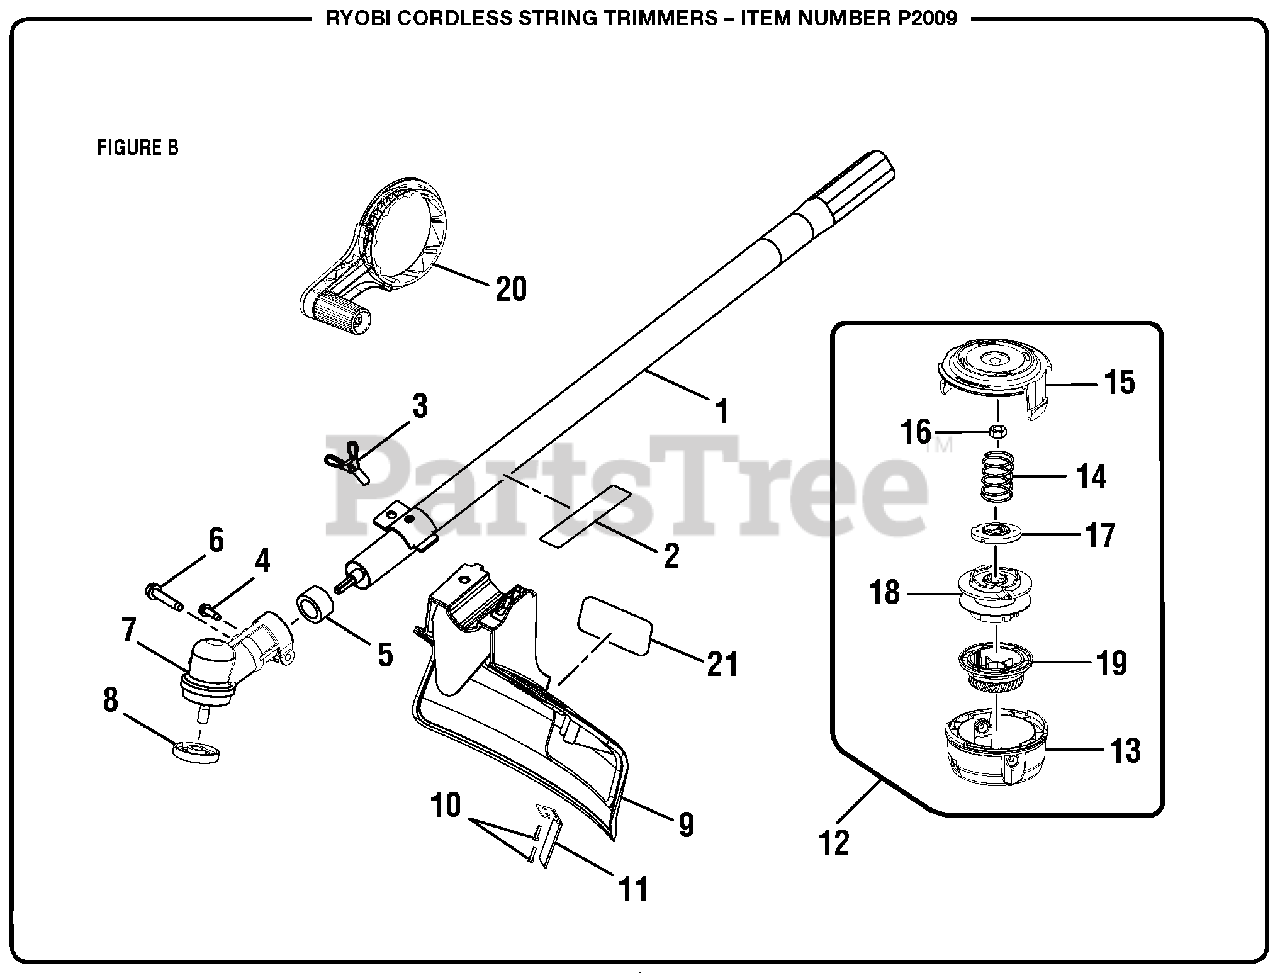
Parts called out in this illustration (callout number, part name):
1	Lower Boom Assembly
2	Logo Label (Shaft)
3	Wing Screw
4	Screw (10-24 x 5/8 in., Hex Washer Hd. S.T.)
6	Screw (1/4-20 x 1-1/4 in., Hex Washer Hd. S.T.)
7	Gear Head Assembly
8	Flanged Washer
9	Grass Deflector Assembly
10	Screw (M4 x 12 mm)
11	Line Cut-Off Blade
12	Trimmer Head Assembly (.080)
13	Lower Housing
15	Upper Housing
16	Hex Flange Nut (M8, Left Hand)
17	String Guide
18	Spool Assembly
19	Bump Knob (Green)
20	Crank Handle Assembly
21	Logo Label (Guard)
